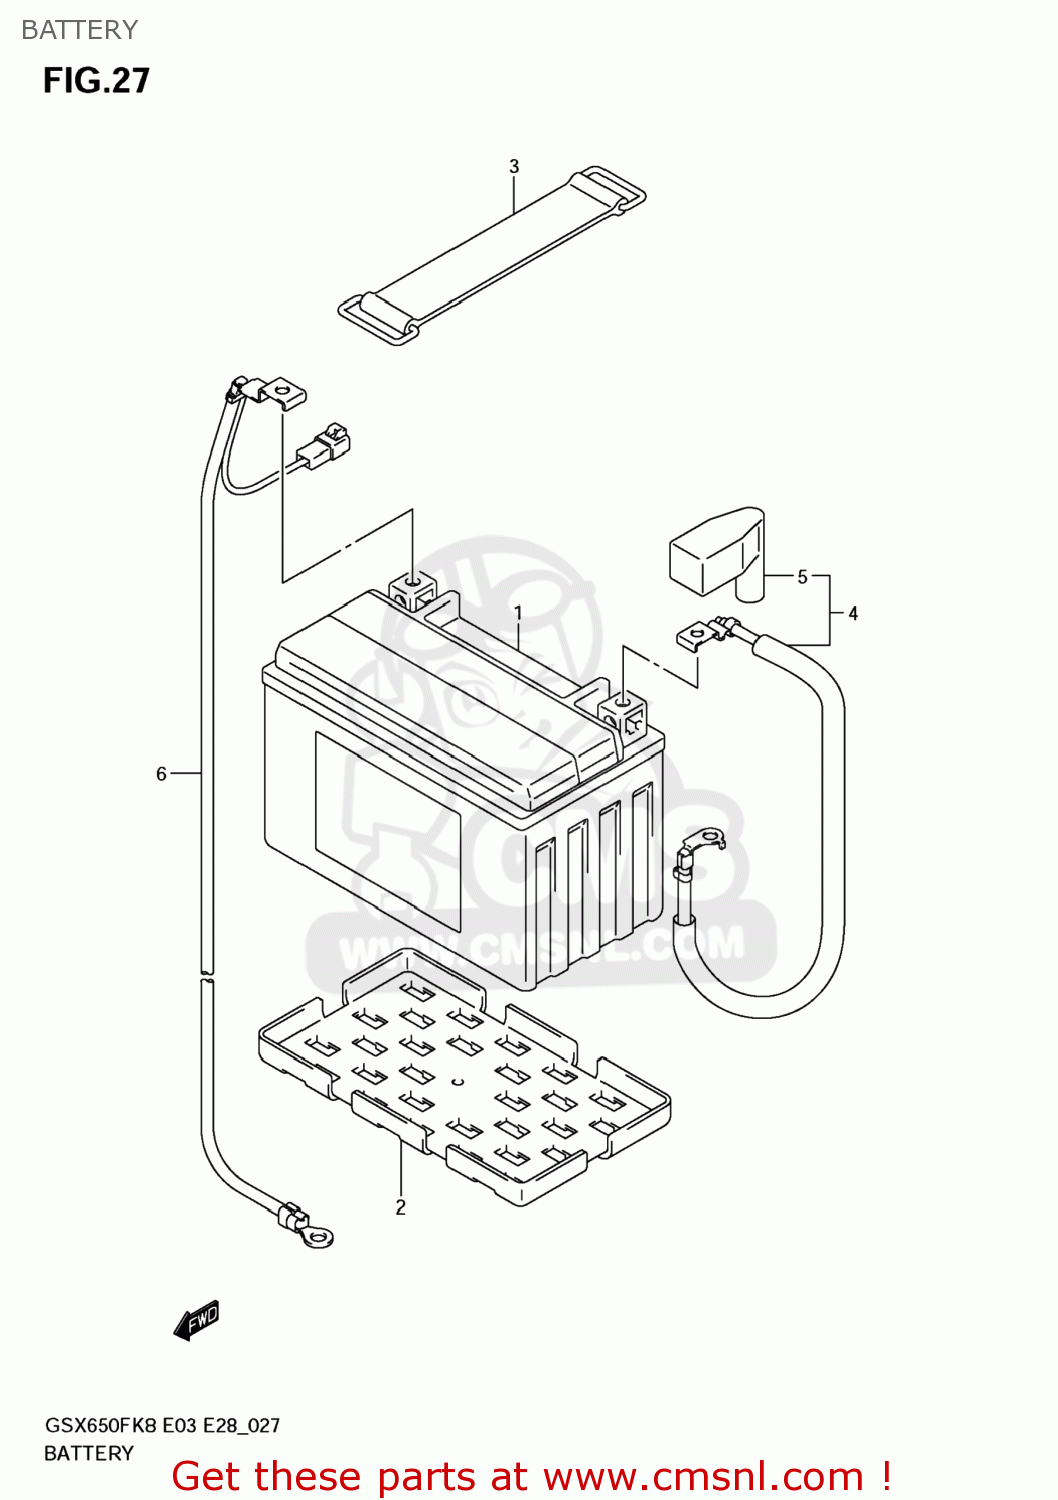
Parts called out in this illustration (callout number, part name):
1	BATTERY ASSY(YTX9-BS,12V8AH)
2	PROTECTOR,BATTERY
3	BAND
4	WIRE,BATTERY PLUS LEAD
5	CAP,BATTERY PLUS LEAD
6	WIRE,BATTERY MINUS LEAD
